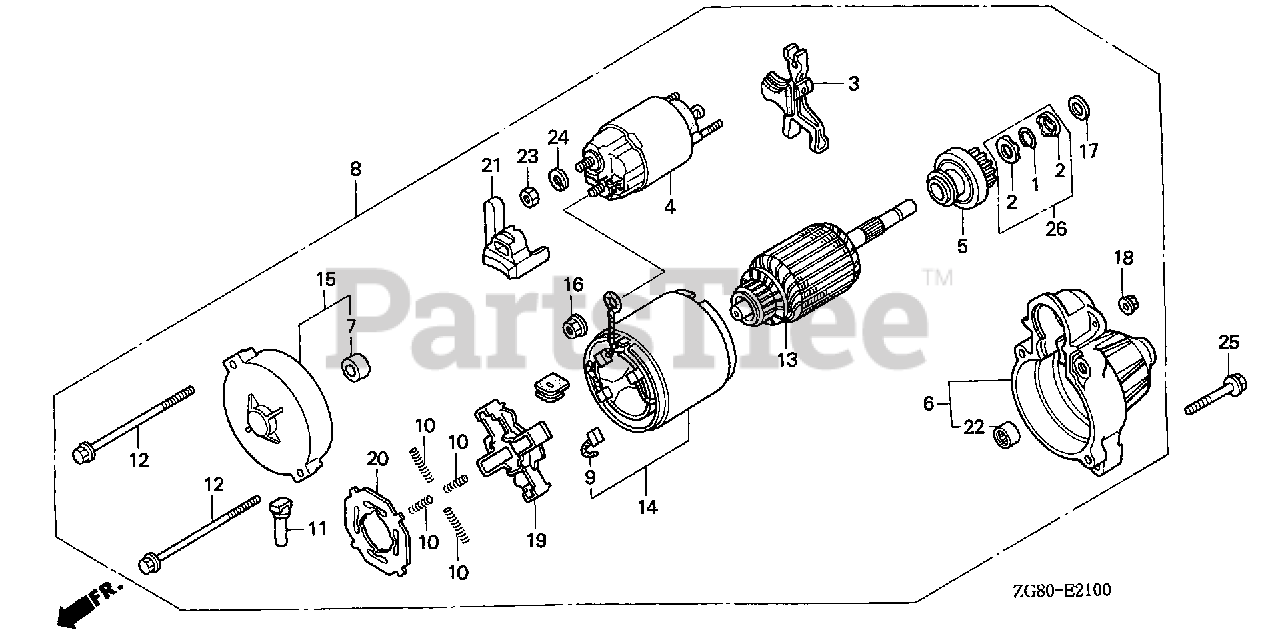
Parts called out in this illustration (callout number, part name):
1	RING, SNAP (DENSO)
2	COLLAR SET, CLUTCH STOP
3	LEVER, PINION DRIVE
4	SWITCH ASSY., MAGNETIC
5	CLUTCH, OVERRUNNING
6	HOUSING, SIDE DRIVE
8	STARTER MOTOR ASSY.
10	SPRING, BRUSH
12	BOLT, THROUGH
15	FRAME, COMMUTATOR END
16	NUT, HEX. (8MM)
17	WASHER
19	HOLDER, BRUSH
20	INSULATOR, BRUSH HOLDER
21	COVER, TERMINAL
23	NUT, HEX. (8MM)
24	WASHER, SPRING (8MM)
25	BOLT, FLANGE (8X40)
26	COLLAR SET, CLUTCH STOP
